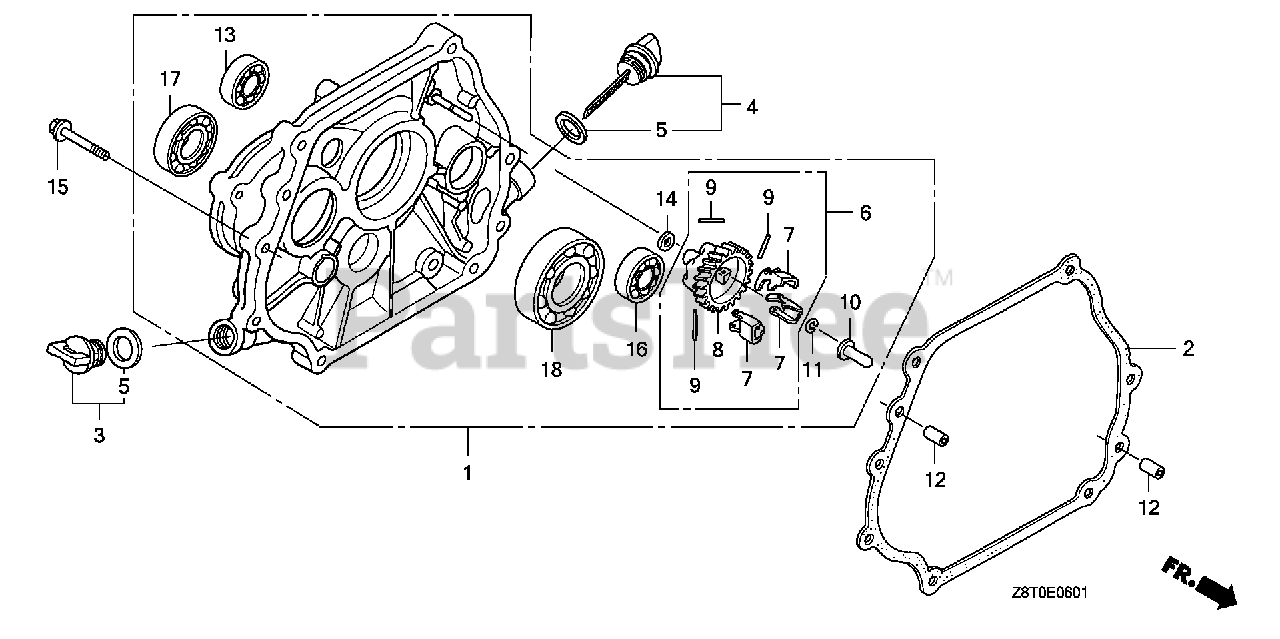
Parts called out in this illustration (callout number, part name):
1	COVER ASSY., CRANKCASE (L-TYPE)
2	GASKET, CRANKCASE COVER
3	CAP ASSY., OIL FILLER
4	CAP ASSY., OIL FILLER
5	GASKET, OIL FILLER CAP
6	GOVERNOR ASSY.
7	WEIGHT, GOVERNOR
8	HOLDER, GOVERNOR WEIGHT
9	PIN, GOVERNOR WEIGHT
10	SLIDER, GOVERNOR
11	CLIP, GOVERNOR HOLDER
12	PIN, DOWEL (8X12)
13	BEARING, RADIAL BALL (6202)
14	WASHER, PLAIN (6MM)
15	BOLT, FLANGE (8X40) Use up to Engine SN 1003236.
16	BEARING, RADIAL BALL (6202)
17	BEARING, RADIAL BALL (6204)
18	BEARING, RADIAL BALL (6207)
